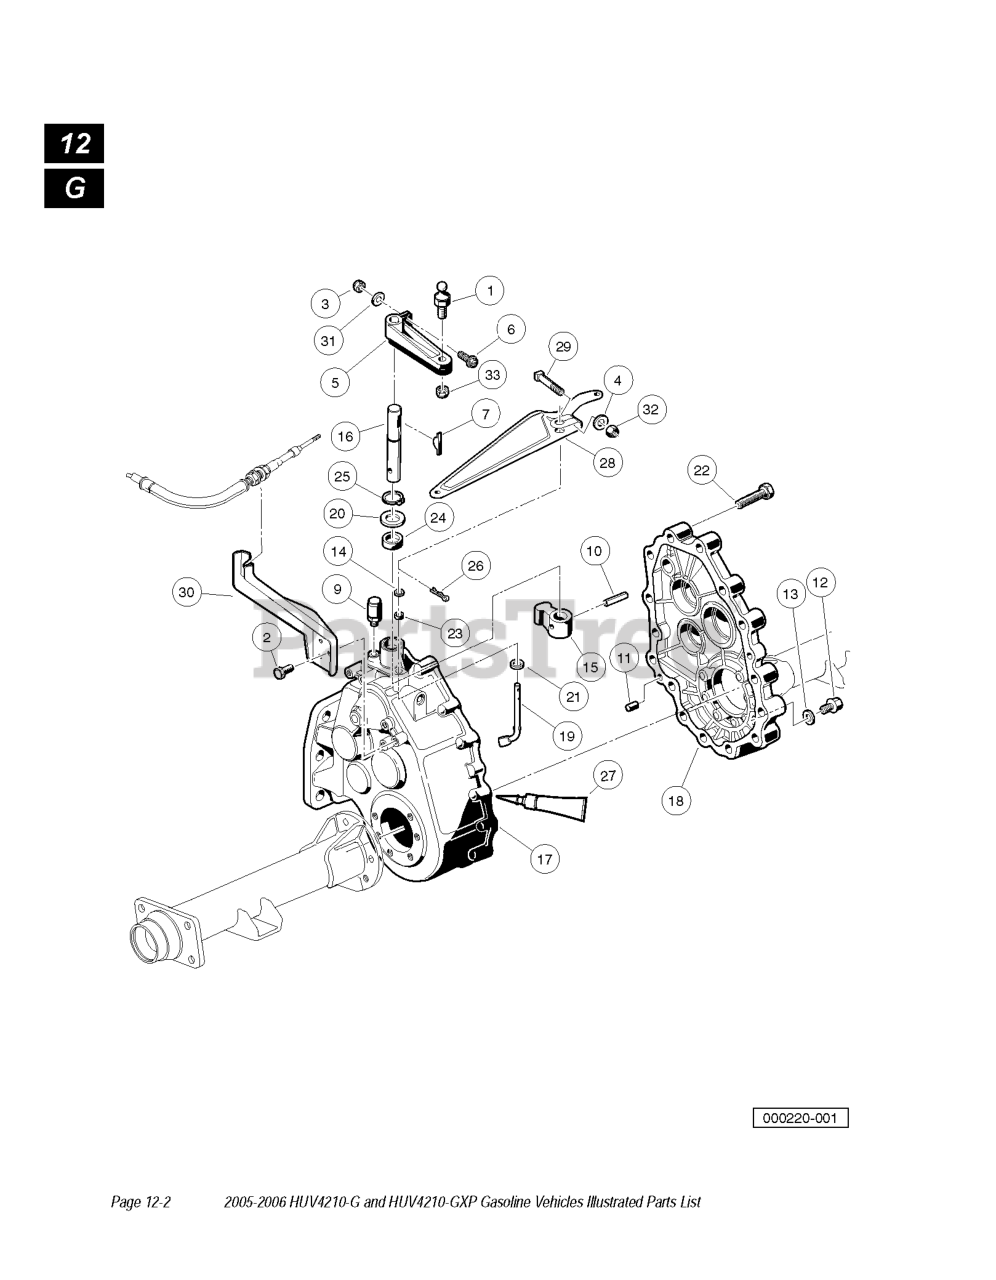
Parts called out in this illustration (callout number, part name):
2	SCREW HX TYP TT
5	TRANSMISSION SHIFT LEVER
6	SCREW, #1--32 X .75 HX HD MACH
7	KEY, WOODRUF
8	TRANSAXLE, 11.77 RATIO
13	GASKET, DRAIN PLUG
14	WASHER, M6 FLAT
15	LEVER - CHANGE
16	SHAFT-CHANGE
17	CASE - GEAR
18	CASE - GEAR
22	SCREW, M8-1.25 X 40MM HEX HEAD
25	RING, INTERNAL RETAINING
26	PIN, COTTER
27	SEALANT
28	ARM, GOVERNOR
29	SCREW, 1/4-20 X 1.00 SQ HEAD
30	SHIFTER BRACKET
31	WASHER FLAT
32	LOCKNUT, 1/4-20 NYLON INSERT
33	LOCKNUT, 1/4-28 NYLON INSERT
